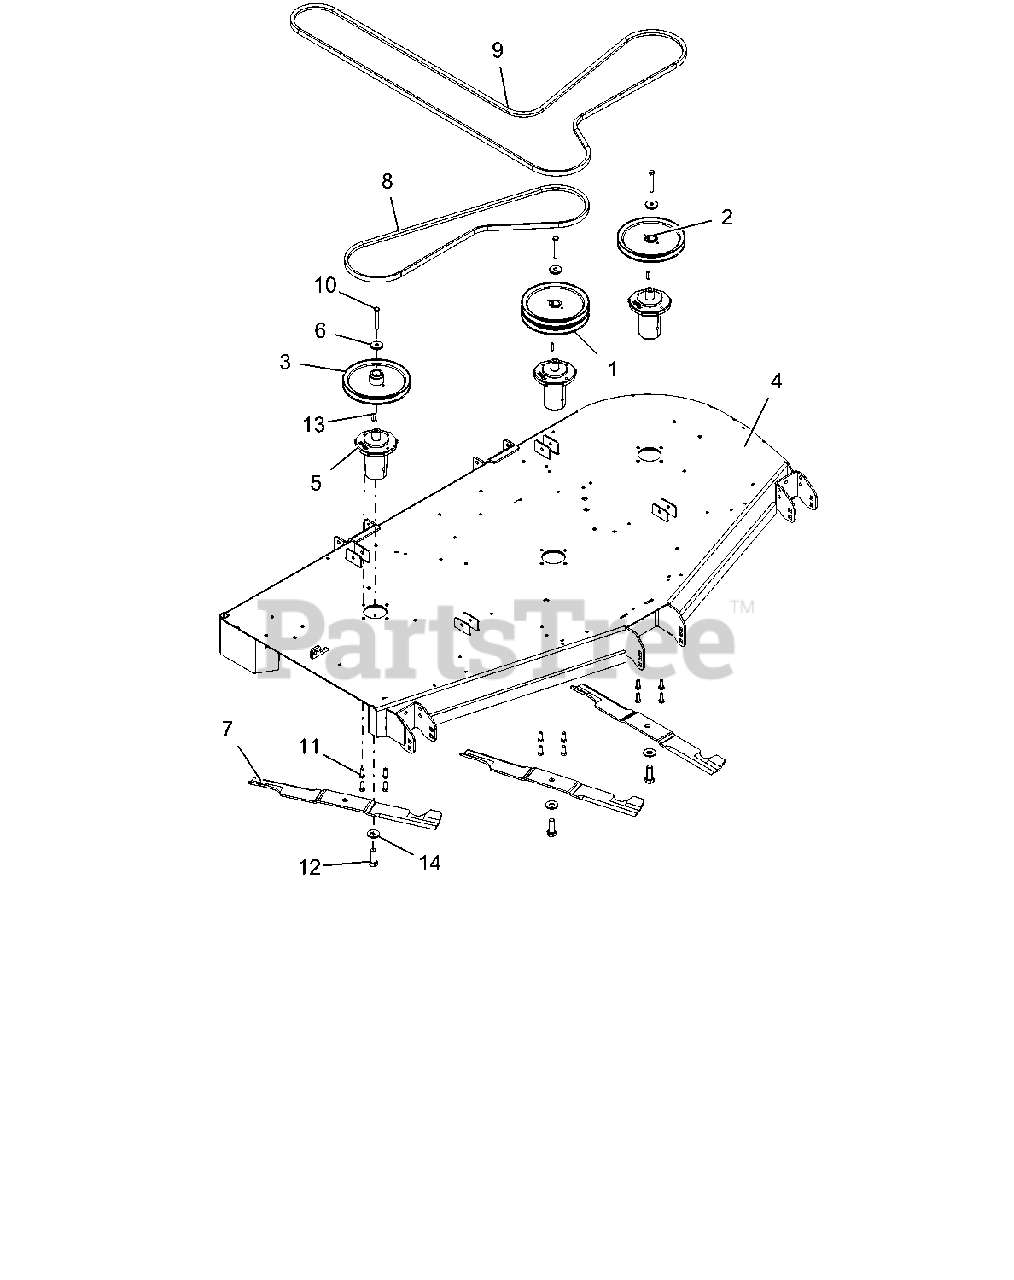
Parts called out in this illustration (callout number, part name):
1	SHEAVE-DOUBLE 1.00"ID X 8.25"OD-BLACK
2	SHEAVE-SINGLE 1.00" X 8.25" OD-BLACK
3	SHEAVE, SINGLE 1.00" ID X 8.25" OD-BLACK
4	WLDMT, 72" SIDE DISCHARGE DECK
5	ASM, SPINDLE - DUCTILE
6	RETAINER, SHEAVE SPINDLE
7	BLADE, 24.50" X .250" MOWER
8	V-BELT, B-COGGED
9	V-BELT, HB SECTION 132.3
10	BLT-HEX .38-16X2.75 GR8 YWZC
11	BLT-HEX .38-16X1.00 GR5 YWZC EP30
12	BLT-HEX .625-18X1.75 GR8 YWZC
13	KEY-SQ .250X.250X1.00 RC 40-50
14	WSHR, BLVL-.63X1.625X.14
